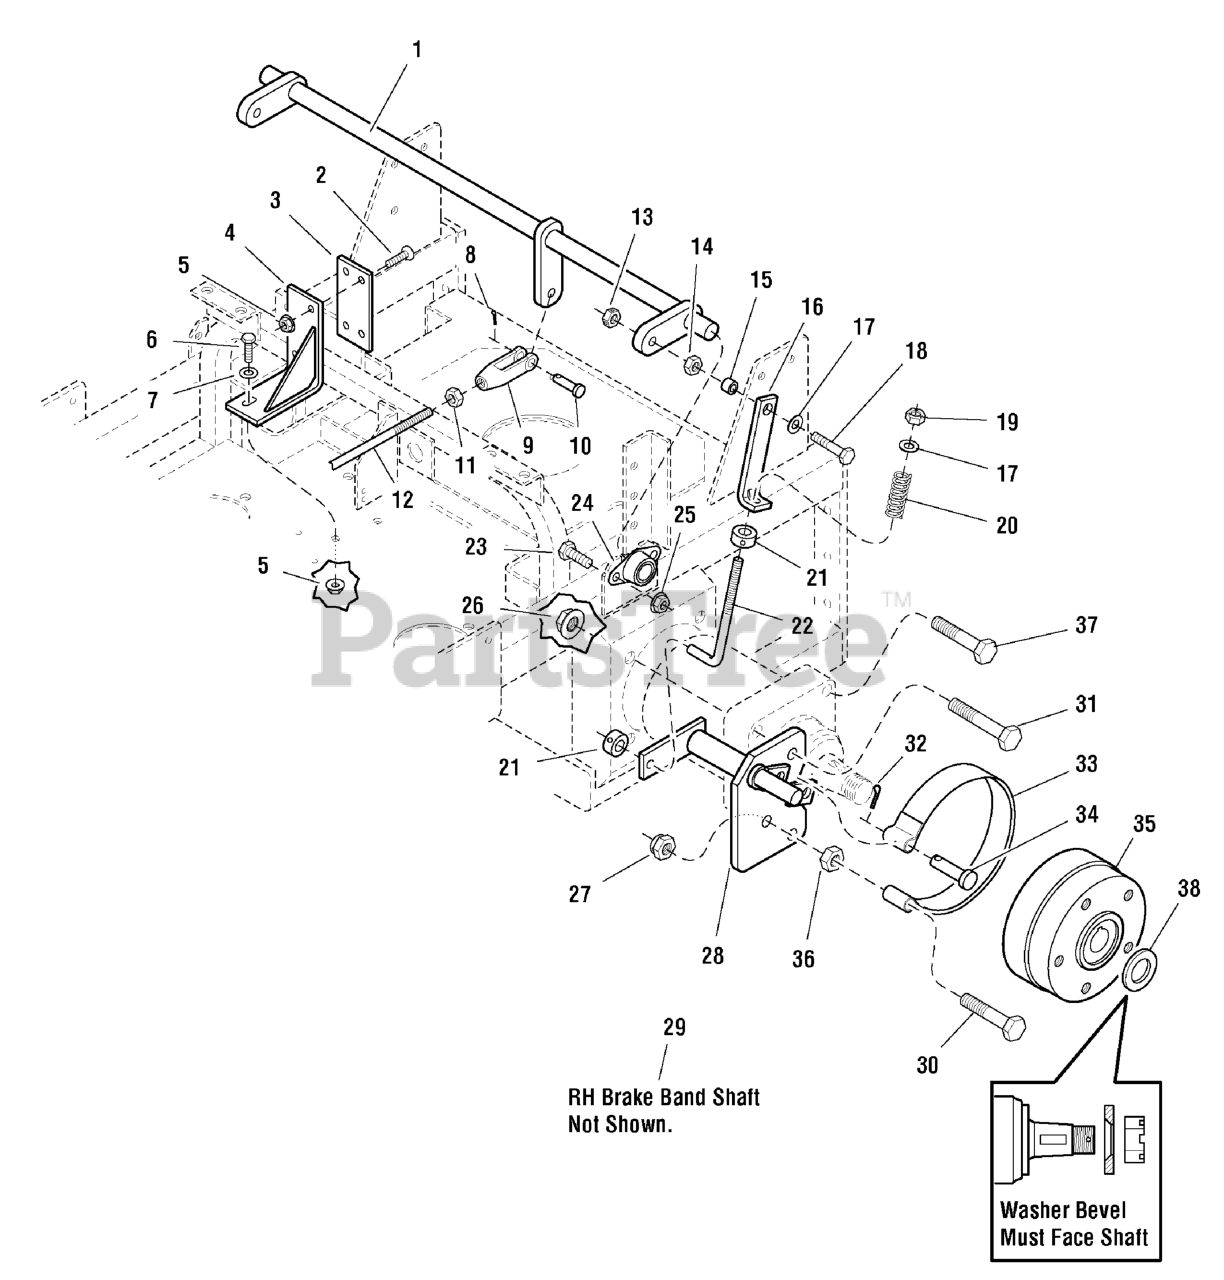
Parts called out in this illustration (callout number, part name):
1	BRAKE CROSS SHAFT
2	SCREW, 5/16-18 X 1 PHILLIPS HD, BZ
3	FRICTION PLATE
4	SUPPORT, Brake Shaft
5	NUT, 5/16-18 HEX SERRATED FLANGE (SMALL)
6	BOLT, 5/16-18 X 1 GD5 YZ
7	WASHER, 5/16" SAE
8	PIN, 3/32 X 0.750, COT, ZINC/CLEAR
9	CLEVIS, 3/8-24, Plastic
10	CLEVIS PIN, 3/8 x 1
11	NUT, 3/8-24 Hex
12	BRAKE CONNECTING ROD
13	NUT, 3/8-16 Hex Side Lock
14	NUT, 3/8-16 Hex
15	SPACER, .38 x .50 x .27
16	LINK, BRAKE LOCK - BLK
17	WASHER, 3/8 SAE
18	BOLT, 3/8-16 X 1-1/2" GD5 CZ
19	NUT, 3/8-16 Hex Top Lock
20	SPRING, Compression
21	COLLAR, 3/8" Set
22	ROD, Brake Adjustment
23	BOLT, 3/8-16 X 3/4" GD5 CZ
24	BEARING, Flange
25	NUT, 3/8-16 Hex Serrated Flange
26	NUT, 1/2-20 Hex Flange Lock
27	NUT, 1/2-13 HEX NYLON LOCK
28	BRAKE BAND SHAFT-LH
30	BOLT, 1/2-13 X 3" GD5 CZ
31	BOLT, 1/2-20 x 3
32	COTTER PIN, 3/16" x 1-1/4"
33	BRAKE BAND
34	CLEVIS PIN, 1/2 x 2
35	BRAKE HUB
36	NUT, 1/2-13 Hex
37	BOLT, 1/2-20 X 2-1/2" GD5 CZ
38	WASHER, 1 x 2
